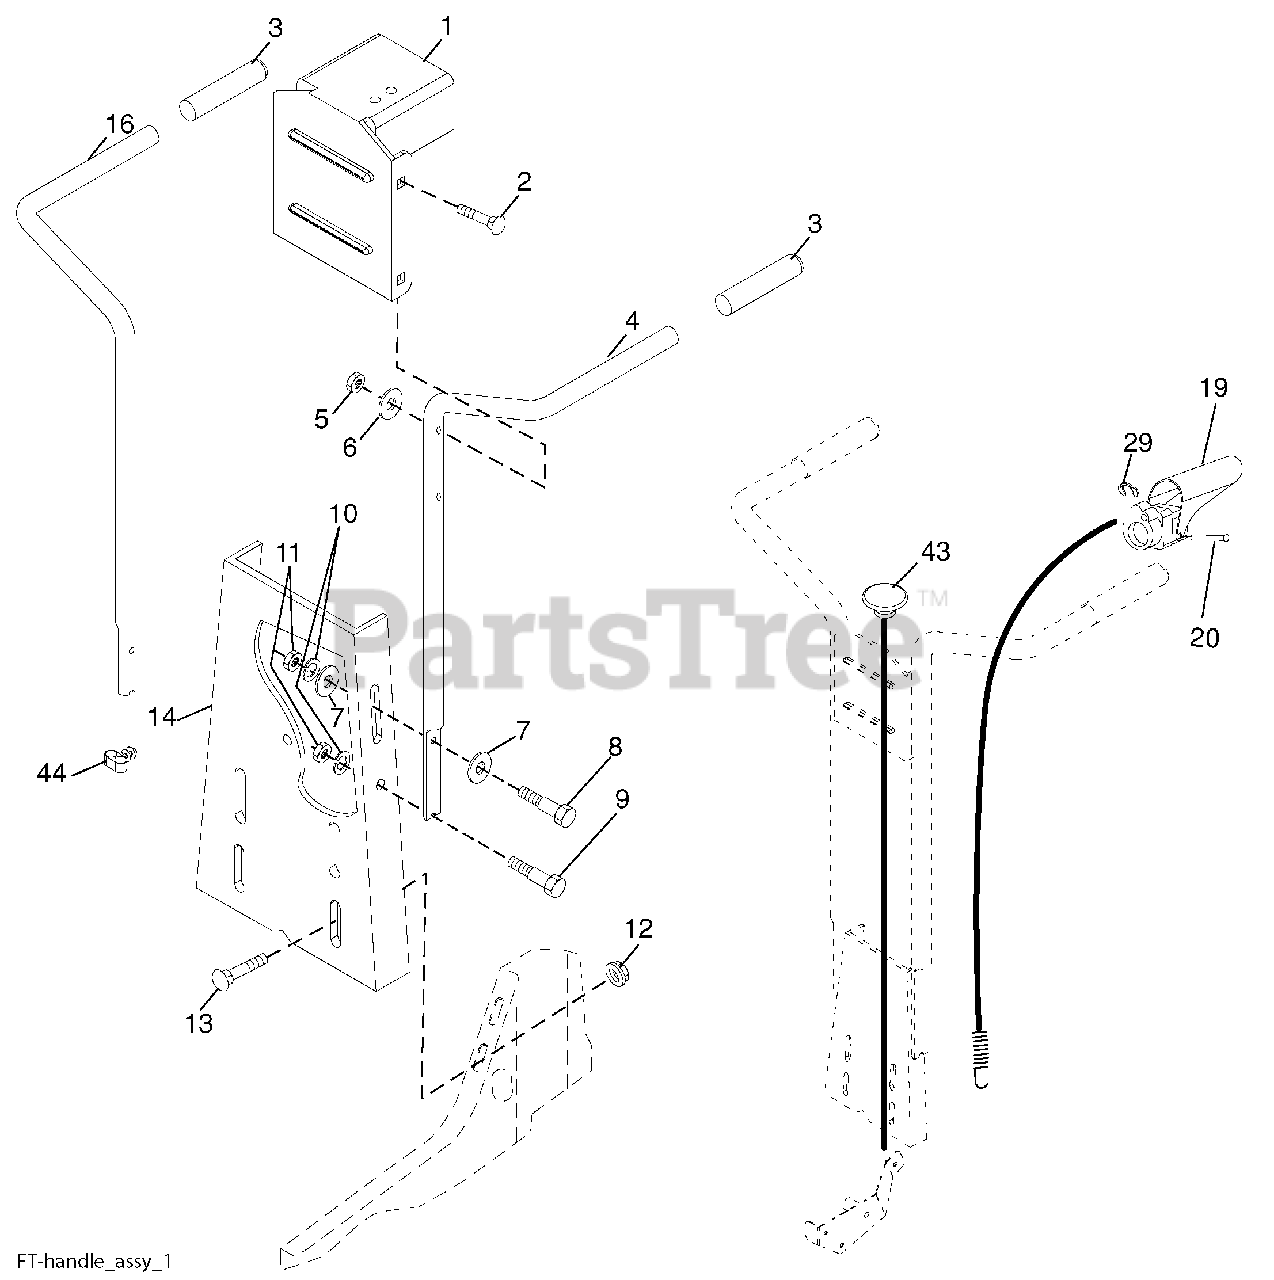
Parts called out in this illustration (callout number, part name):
1	Bracket, Handle
2	Bolt, Carriage 5/16-18 x 1-1/2
3	Grip, Handle
4	Handle, L.H.
5	Nut, Hex, Crownlock 5/16-18
6	Washer 11/32 x 11/16 x 16 Ga.
7	Washer 3/8 x 7/8 x 14 Ga.
8	Bolt, Hex Head 5/16-18 x 1-1/4
9	Bolt, Hex Head 5/16-18 x 1
10	Washer, Lock 5/16
11	Nut, Hex 5/16-18
12	Nut, Hex, Flanged 5/16-18
13	Bolt, Carriage, Gr. 5 5/16-18 x 3/4
14	Panel, Handle
16	Handle, R.H.
19	Tine Control Lever Assembly
20	Pin, Pivot
29	Retaining Ring
43	Cable Assembly, Reverse
44	Clip
